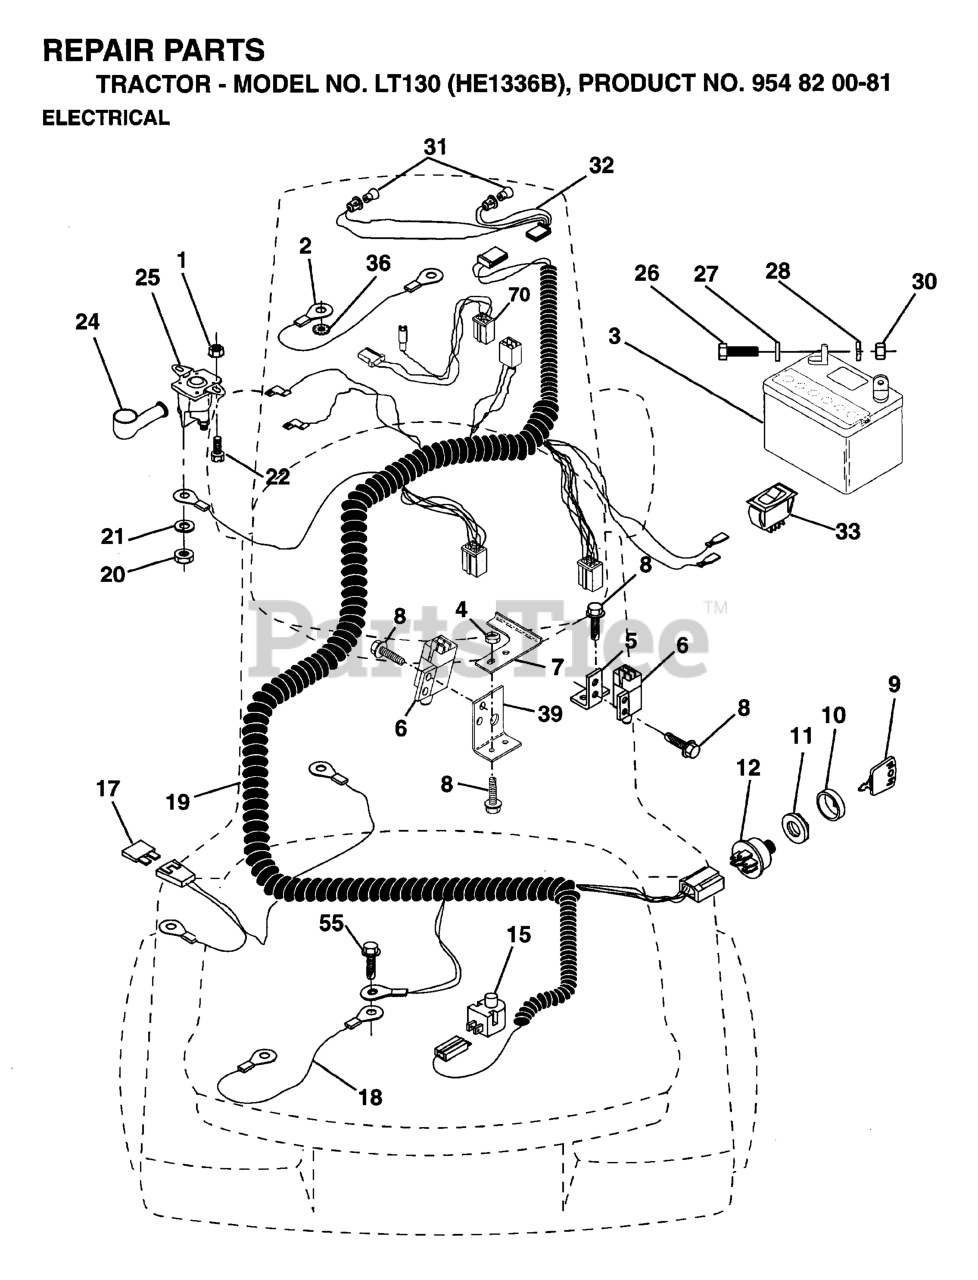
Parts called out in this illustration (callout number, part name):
1	Nut, Keps Blk Hex 1/4-20 UNC
2	CABLE.BATTERY.6GA.16"RED
3	BATTERY
5	BRACKET LT
6	SWITCH INTERLOCKT
7	KEEPER, ACTUAT. L.R.
9	KEY MLD GEN DELTA
10	COVER SWITCH KEY
11	NUT, IGNITION
12	IGNITION SWITCH
15	RP.SWITCH.PLUNGER.NC.GRAY
18	CABLE ASSY
19	HARNESS IGN LR NLA
20	NUT
21	LOCKWASHER
22	BOLT
24	TERMINAL COVER
25	SOLINOID
26	BOLT.HEX.1/4.X.3/4.DICHROMATE
28	LOCKWASHER
30	NUT
32	HARNESS HEADLIGHT
36	Washer, Lock, Internal Tooth 1/4
55	Screw 5/16-18 x 1/2 Hex, Self Tapping 5/16-18 x 1/2
70	HARNESS, ENGINE
